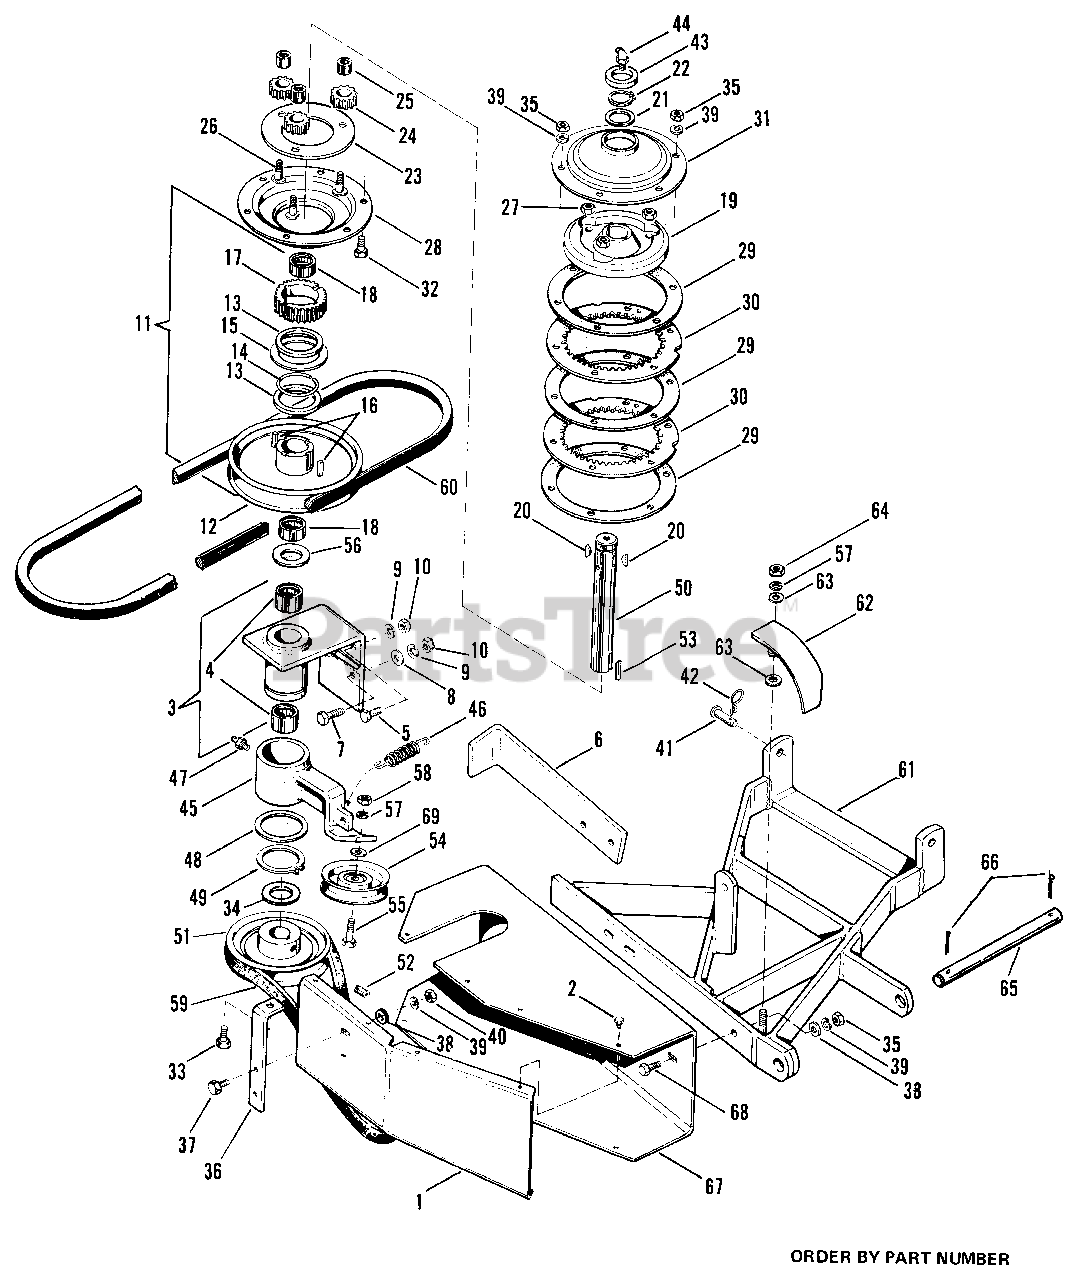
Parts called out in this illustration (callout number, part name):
2	Self Tapping Screw
3	Tube & Support Assy. w/Bearings
5	Hex Capscrew, 5/16"-18 x 1" lg.
7	Hex Capscrew, 5/16"-18 x 1-1/4"
8	Plain Washer, 1/4"
9	Lockwasher, 5/16"
10	Hex Nut, Full, 5/16"-18
11	Pulley and Hub Assembly
12	Hub and Pulley
19	Spider Hub
22	Retaining Ring
23	Ring Bolt
25	Needle Bearing
26	Pinion Pin
27	Hex Nut, Full, Lock 5/16"-18
28	Cover, Left Hand
30	Ring Gear
32	Hex Capscrew, 5/16"-18 x 3/4"
33	Hex Capscrew, 5/16"-18 x 7/8"
34	Thrust Washer
35	Hex Nut, Full, 5/16"-18
37	Hex Capscrew, 5/16"-18 x 3/4" lg.
38	Plain Washer, 5/16"
39	Lockwasher, 5/16"
40	Hex Nut, Full, 5/16"-18
41	Pin
42	Spring Clip
44	Grease Fitting
45	Arm Assembly
47	Grease Fitting
48	Washer, Special
49	Retaining Ring
52	Set Screw, 3/8"-16 x 3/4"
54	Idler Pulley
55	Hex Capscrew, 3/8"-16 x 1-1/4"
56	Thrust Washer
57	Lockwasher, 3/8"
58	Hex Nut, Full, 3/8"-16
59	V-Belt (Mower Drive)
61	Frame Assembly
62	Belt Guard Assembly
63	Plain Washer, 3/8"
64	Hex Nut, Full, 3/8"-16
65	Hinge Shaft
66	Cotter Pin, 3/16" x 1" lg.
68	Hex Capscrew, 5/16"-18 x 1" lg.
69	Plain Washer, 5/16"
